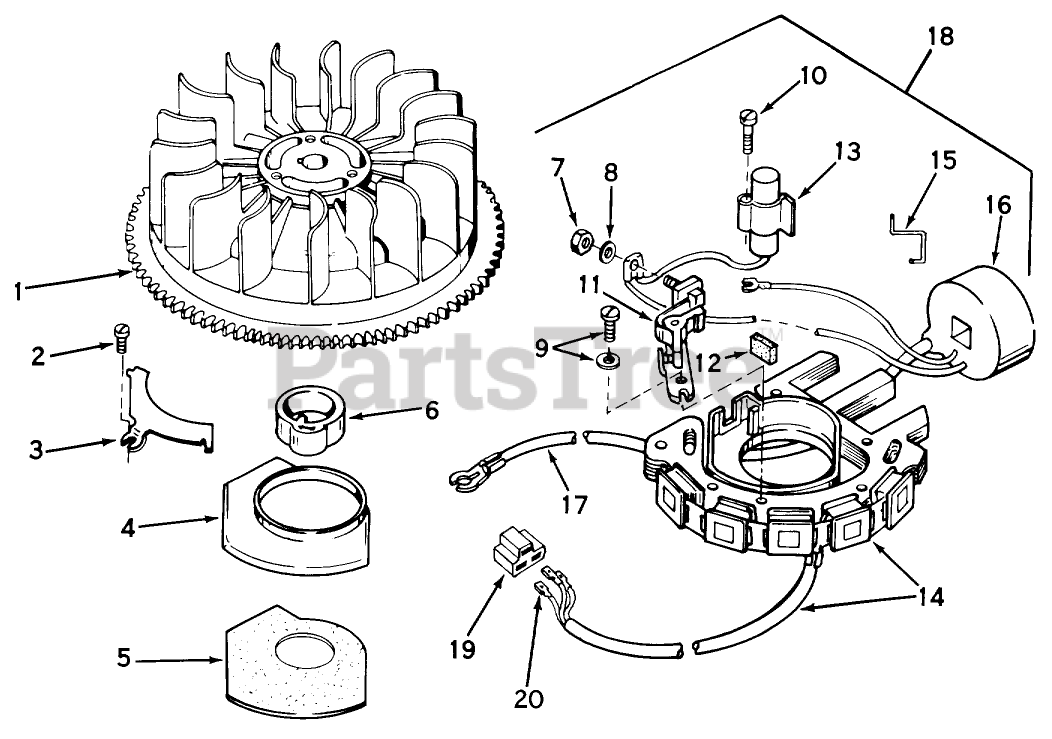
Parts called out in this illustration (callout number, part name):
1	Flywheel
2	Screw, Dust Cover
3	Clamp, Dust Cover
4	Cover, Dust
5	63563A GIL MWR ATTC
6	Cam, Breaker
7	DECAL
8	Washer
9	Breaker Screw
10	Condenser Screw
11	Contact Assy., Breaker
12	Felt,Cam Wiper
13	Condenser
14	Stator Core Generating Coils (Incl. Nos. 19 20)
15	Clip, Coil
17	Wire, Lead
18	Stator Plate Assy. (Incl. Nos. 2 thru 5, 7 thru 17, 19 20)
19	Connector, Pyramid
20	Terminal
